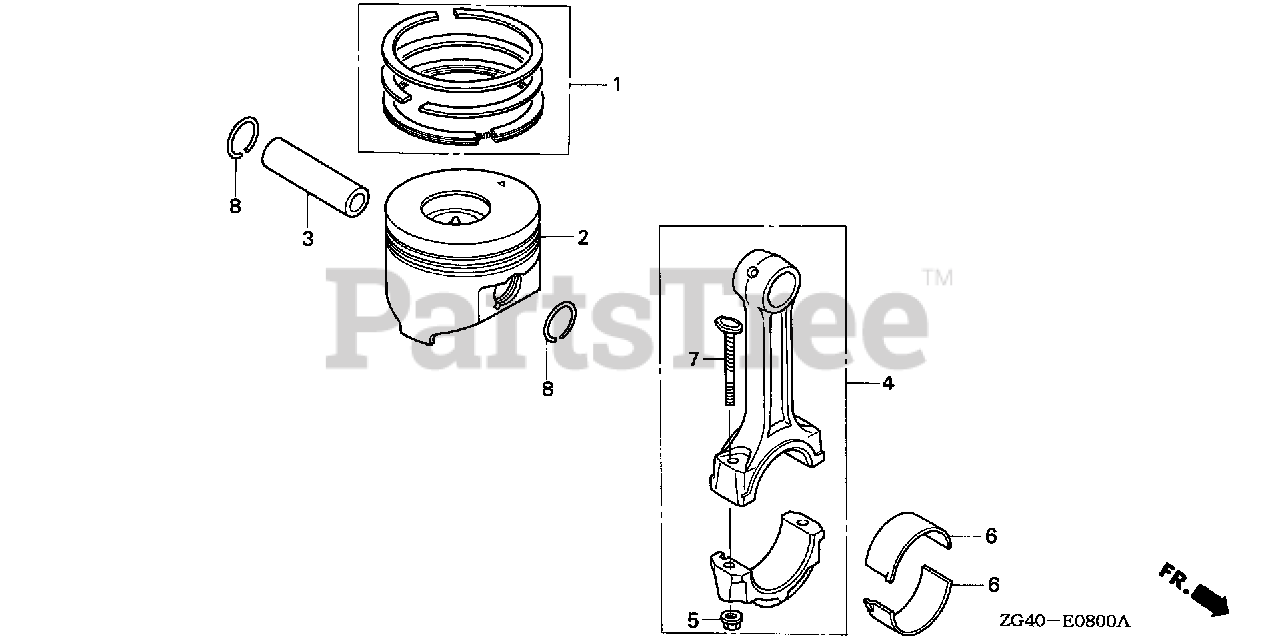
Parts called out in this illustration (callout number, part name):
1	RING SET, PISTON (STD)
1	RING SET, PISTON (0.25)
1	RING SET, PISTON (0.50)
1	RING SET, PISTON (0.75)
2	PISTON (STD)
3	PIN, PISTON
4	ROD ASSY., CONNECTING
5	NUT, CONNECTING ROD
6	BEARING A, CONNECTING ROD (BLUE)
6	BEARING B, CONNECTING ROD (BLACK)
6	BEARING C, CONNECTING ROD (BROWN)
6	BEARING D, CONNECTING ROD (GREEN)
6	BEARING E, CONNECTING ROD (YELLOW)
6	BEARING F, CONNECTING ROD (PINK)
6	BEARING G, CONNECTING ROD (RED)
6	BEARING A, CONNECTING ROD
6	BEARING B, CONNECTING ROD
6	BEARING C, CONNECTING ROD
7	BOLT, CONNECTING ROD (NAGOYA RASHI)
8	CLIP, PISTON PIN (1.2X20)
